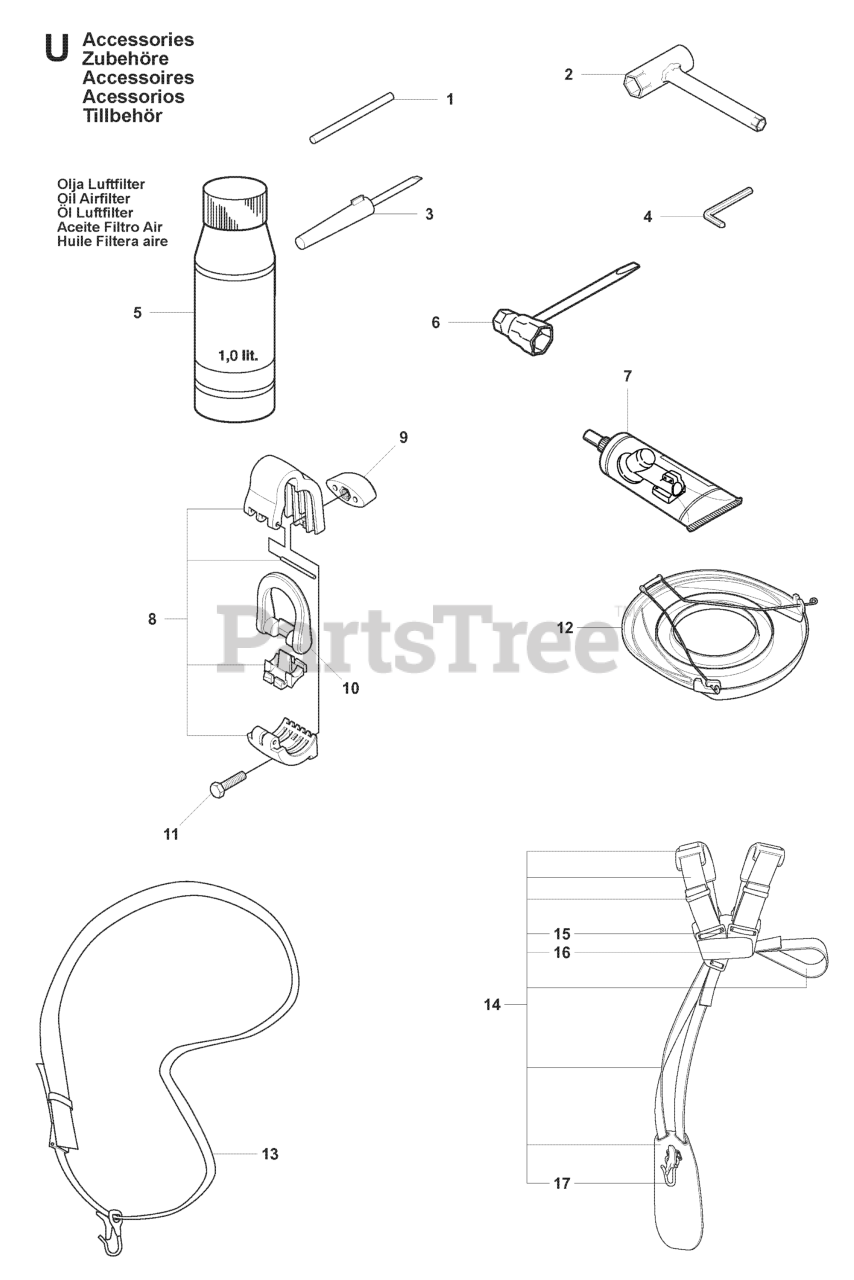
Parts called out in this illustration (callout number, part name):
1	LOCKING PIN
2	COMBI WRENCH
3	SCREWDRIVER
4	L-KEY WRENCH
5	Air Filter Oil 1l.
6	COMBI TOOL
7	BEVEL GEAR GREASE
8	HANGING BRACKET
11	SCREW M6S 5X20
12	BLADE GUARD TRANSPORT
13	Harness-w/o warning
13	Harness - Diagonal with sign
14	Harness w/warning
14	HARNESS DUO
17	HOOK, CPL.
